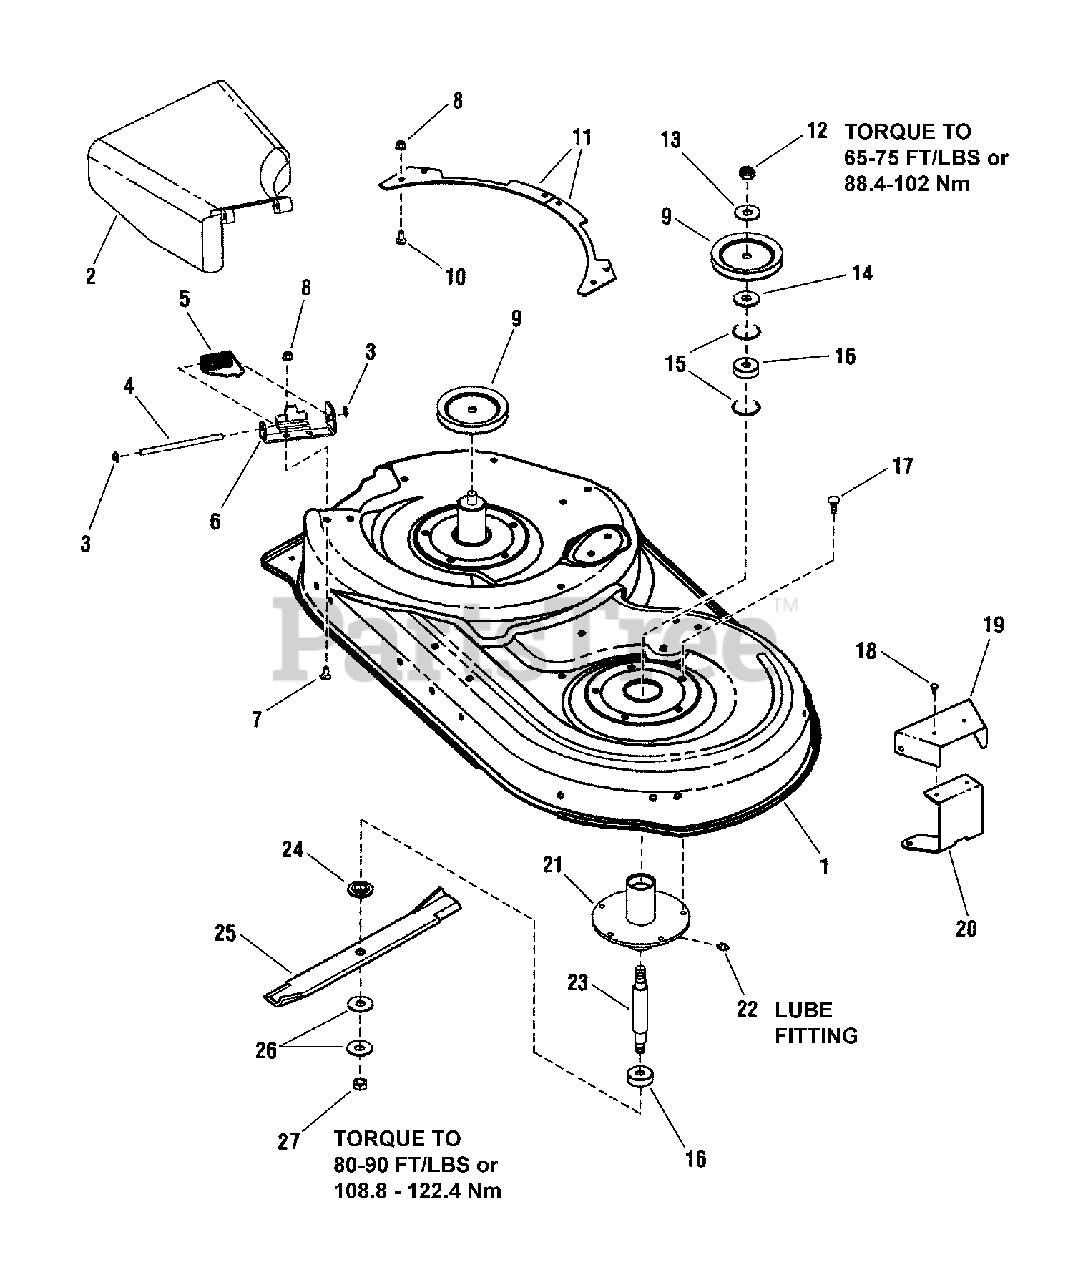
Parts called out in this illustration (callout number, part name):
1	HOUSING, 42" Deck (Smi Orange)
2	ASSEMBLY, Deflector Chute
3	PUSH NUT, 3/8" Pal Cap
4	ROD, Deflector
5	SPRING, Torsion
6	BRACKET, Hinge
7	BOLT, 5/16-18 x 3/4" Round Head Short Square Neck, GR5
8	NUT, 5/16-18 Hex Flange Nyloc
9	PULLEY, Drive, 5-1/2"
10	BOLT, 5/16-18 x 1" Round Head Short Square Neck, GR5
12	NUT, 5/8-18 Hex Jam
13	WASHER, 5/8" Bellville
14	SPACER, Pulley
15	RING, 1.85" Internal Retaining
16	BEARING, Spindle
17	SCREW, 3/8-16 x 3/4" Hex Taptite
18	SCREW, 1/4-20 x 1/2" Hex Washer Head Screw Black (Taptite)
19	COVER, Pulley
20	BRACKET, Arbor Guard
21	WELDMENT, Spindle Housing
22	LUBE FITTING, .250 Drive Type
23	SHAFT, Spindle
24	WASHER, Spindle Blade, Powdered Metal
25	BLADE, 19.64
26	WASHER, 9/16" Bellville
27	NUT, 9/16-18 Hex, GR B
